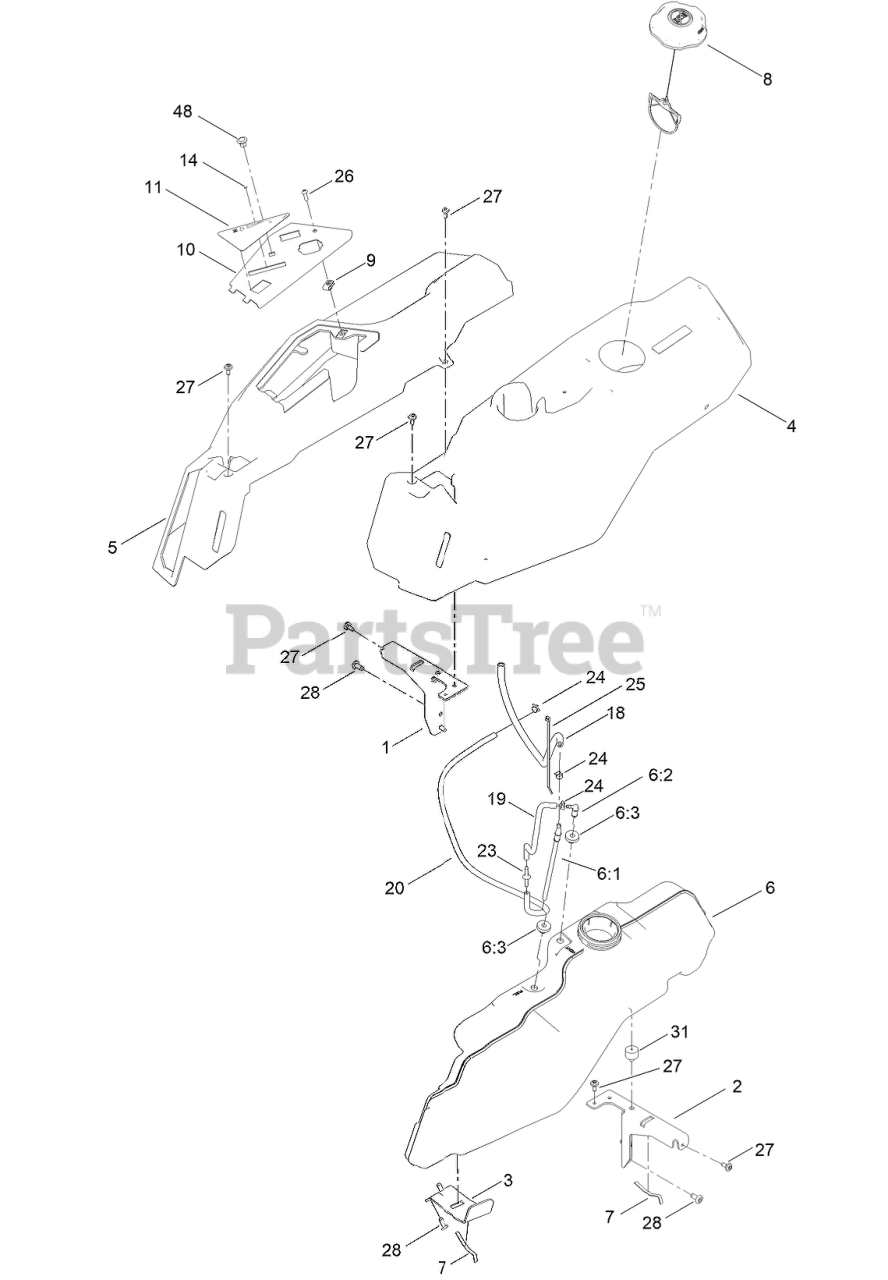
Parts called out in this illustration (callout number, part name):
1	SUPPORT-POD, RH
2	SUPPORT-POD, LH
3	SUPPORT-TANK, FUEL
4	POD-LH
5	POD-RH
6	TANK-FUEL ASM
6:1	CONNECTOR-ELBOW, 90 DEG
6:2	FITTING-ELBOW 90
6:3	BUSHING
7	SPRING
8	CAP-FUEL, RATCHETING
10	PANEL - CONTROL
11	DECAL-PANEL CONTROL
14	CABLE-THROTTLE AND CHOKE
18	HOSE-FUEL
19	HOSE-FUEL
20	HOSE-FUEL
23	ADAPTER ORIFICE
24	CLAMP-HOSE
25	TIE-CABLE
26	SCREW-PRH
27	SCREW-SHOULDER
31	BUMPER-GROMMET
48	PLUG-DASH
